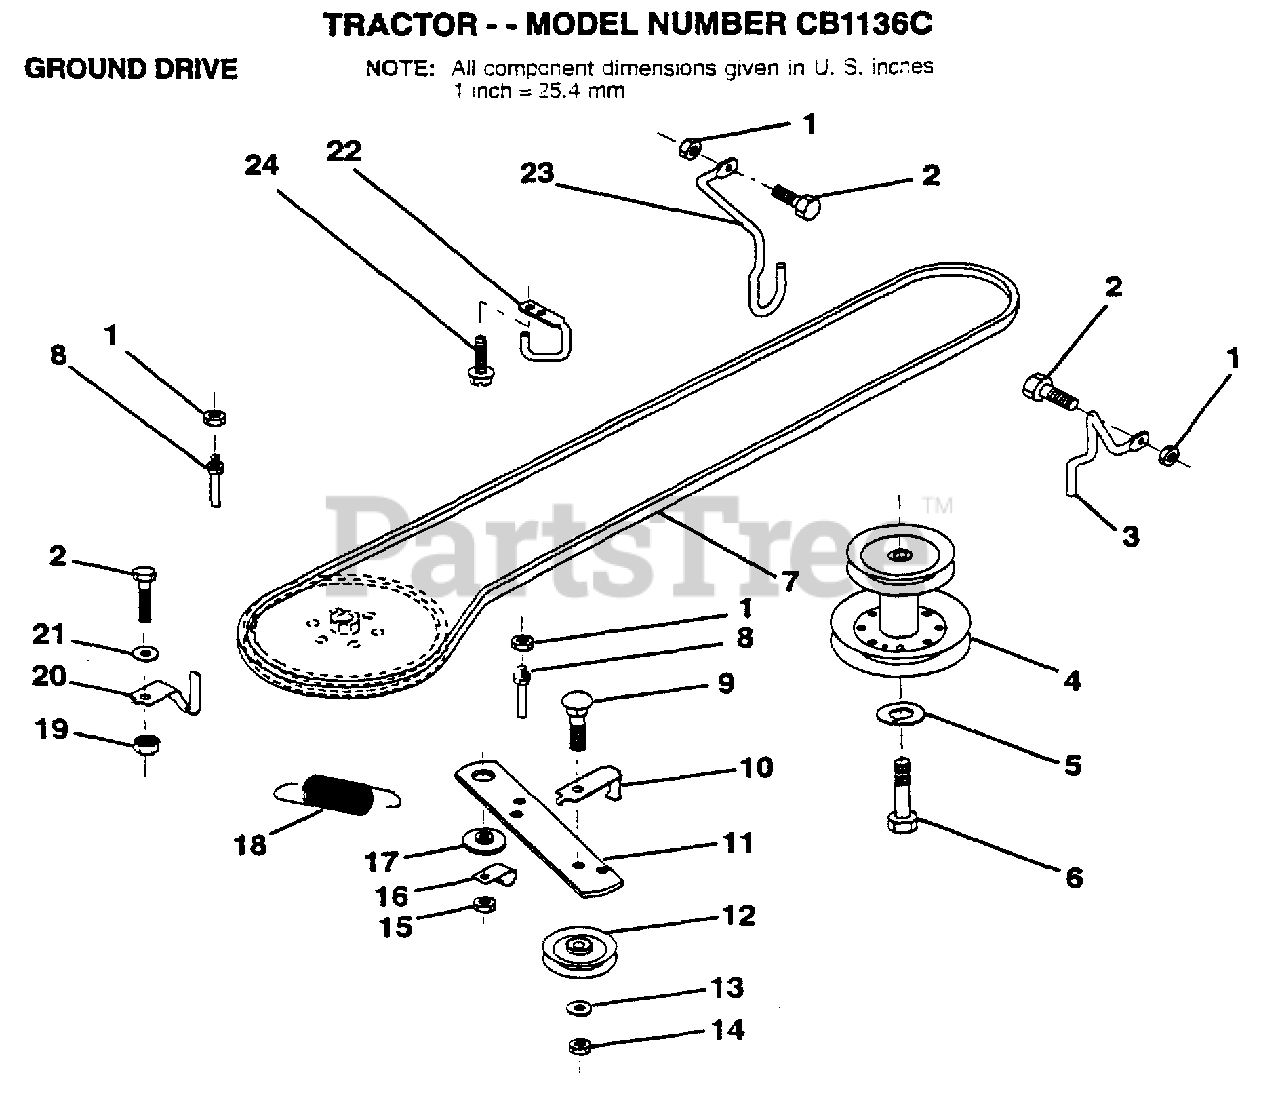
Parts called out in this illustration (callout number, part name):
2	BOLT
3	KEEPER RH
4	PULLEY.ENGINE.LR
5	LOCKWASHER
6	HEX BOLT
7	BELT
8	"KEEPER,DRIVE BELT"
9	BOLT
10	"KEEP,IDLER DR BEL"
11	ARM IDLER CLUT GD
12	PULLEY.IDLER.FLAT
13	WASHER
14	LOCKNUT
16	"CLIP,INSULATOR"
17	SPACER RETAINER
20	KEEPER.BELT.T/A
21	WASHER
22	"KEEPER,FRA DR BEL"
23	KEEPER MOWER LH
24	SCREW
